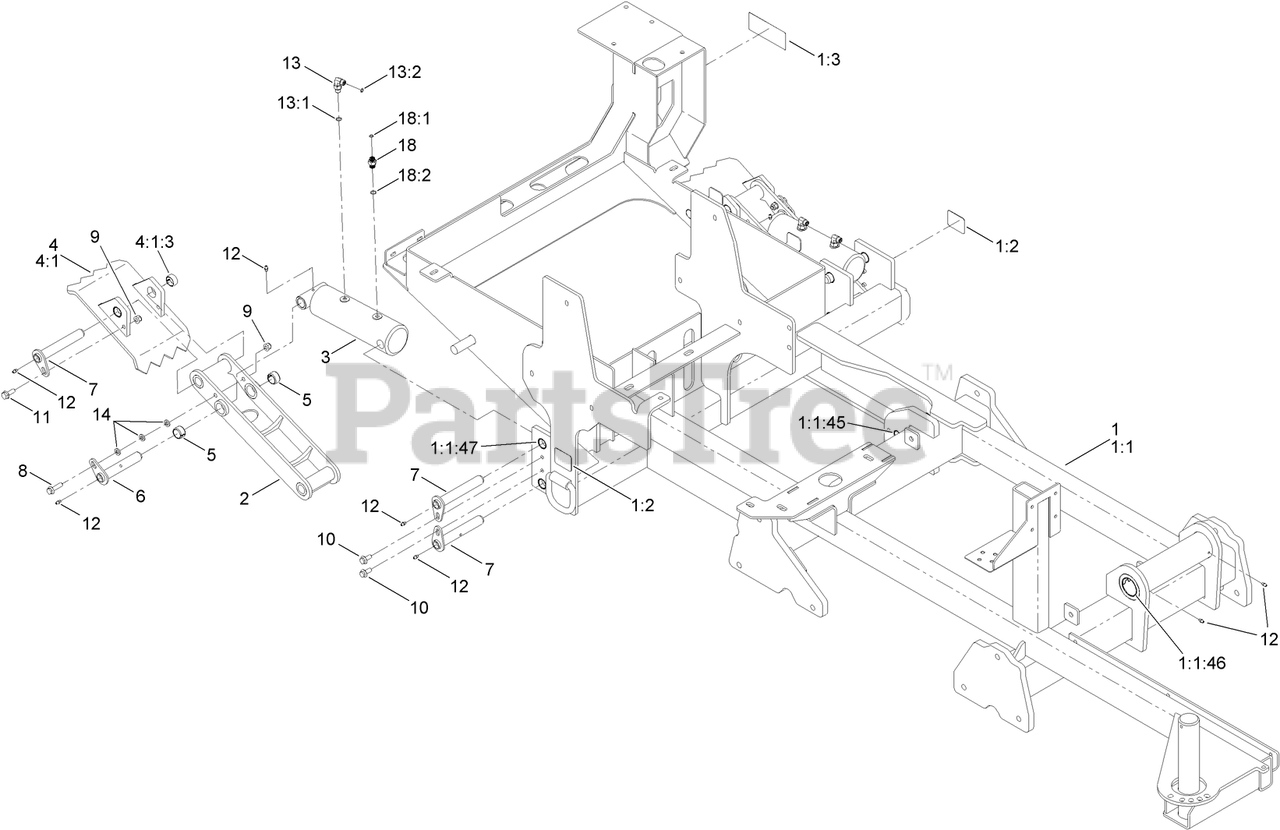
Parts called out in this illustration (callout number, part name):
1	MAIN FRAME ASM
1:1	FRAME-MAIN
1:1:45	BUSHING-SPRING
1:1:46	BUSHING-SPRING
1:1:47	BUSHING-SPRING
1:2	DECAL-TIE DOWN
1:3	DECAL-WARNING, HYDRAULIC PRESSURE
2	LEG-STABILIZER
3	HYD CYLINDER ASM
4	STABILIZER FOOT ASM
4:1	FOOT-STABILIZER
4:1:3	BUSHING-SPRING
5	BUSHING-SPRING
6	PIN-FLAG
7	PIN-FLAG
8	SCREW-HHF
9	NUT-LOCK, NI
10	SCREW-HHF
11	SCREW-HHF
12	FITTING-GREASE
13	FITTING-ELBOW 90
13:1	O-RING
13:2	O-RING
14	SPACER
18	FITTING-STRAIGHT
18:1	O-RING
18:2	O-RING
